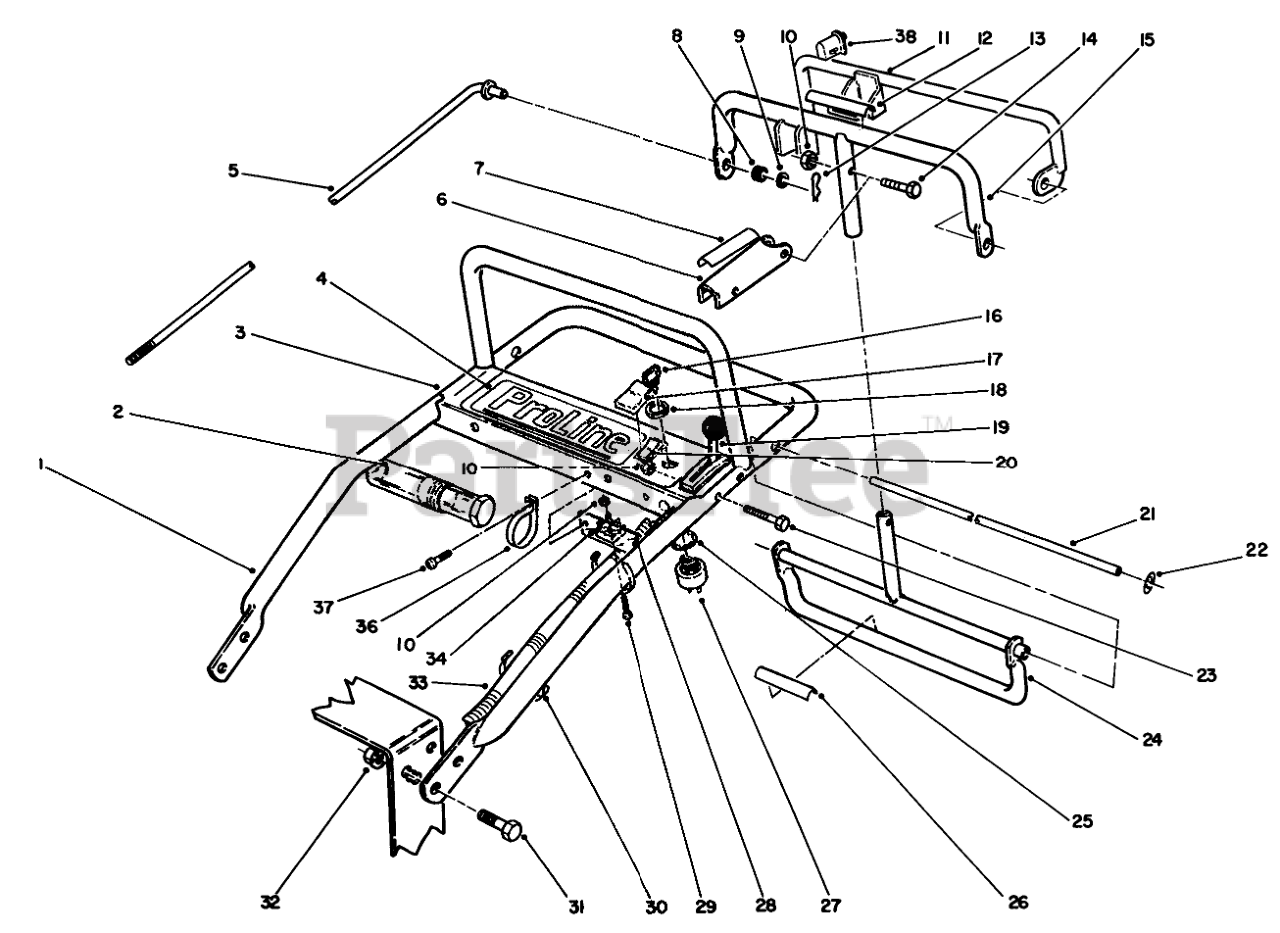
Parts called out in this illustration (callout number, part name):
1	Handle-Upper
2	TUBE-MANUAL
3	Panel-Control
4	DECAL - CONTROL PANEL
5	ROD-CONTROL
6	Lever-Parking Brake
7	DECAL-LEVER, PARKING
8	GROMMET-RUBBER
9	WASHER-FLAT
10	NUT-LOCK, NI
11	Bail
12	DECAL-CONTROL BAR
13	DECAL
14	SCREW-SHH
15	Bar
16	KEY-IGNITION
17	NUT
18	NUT-HH
19	CONTROL-THROTTLE
20	SWITCH
21	PIVOT ROD
22	NUT-PUSH-ON, CIRCULAR
23	SCREW-SHH
24	Control Pivot
25	WASHER-TOOTH, INTERNAL
26	DECAL
27	Switch-Ignition (Incl. Ref. #16, 18, & 25)
28	Panel-Bottom
29	SCREW-HWH
30	TIE-CABLE
31	SCREW-HHF
32	NUT-HF
33	Wire Harness (Ref.)
34	RECTIFIER-BRIDGE
35	SWITCH-BAIL
36	CLAMP-R
37	SCREW-HWHTF
38	BOOT-SWITCH
